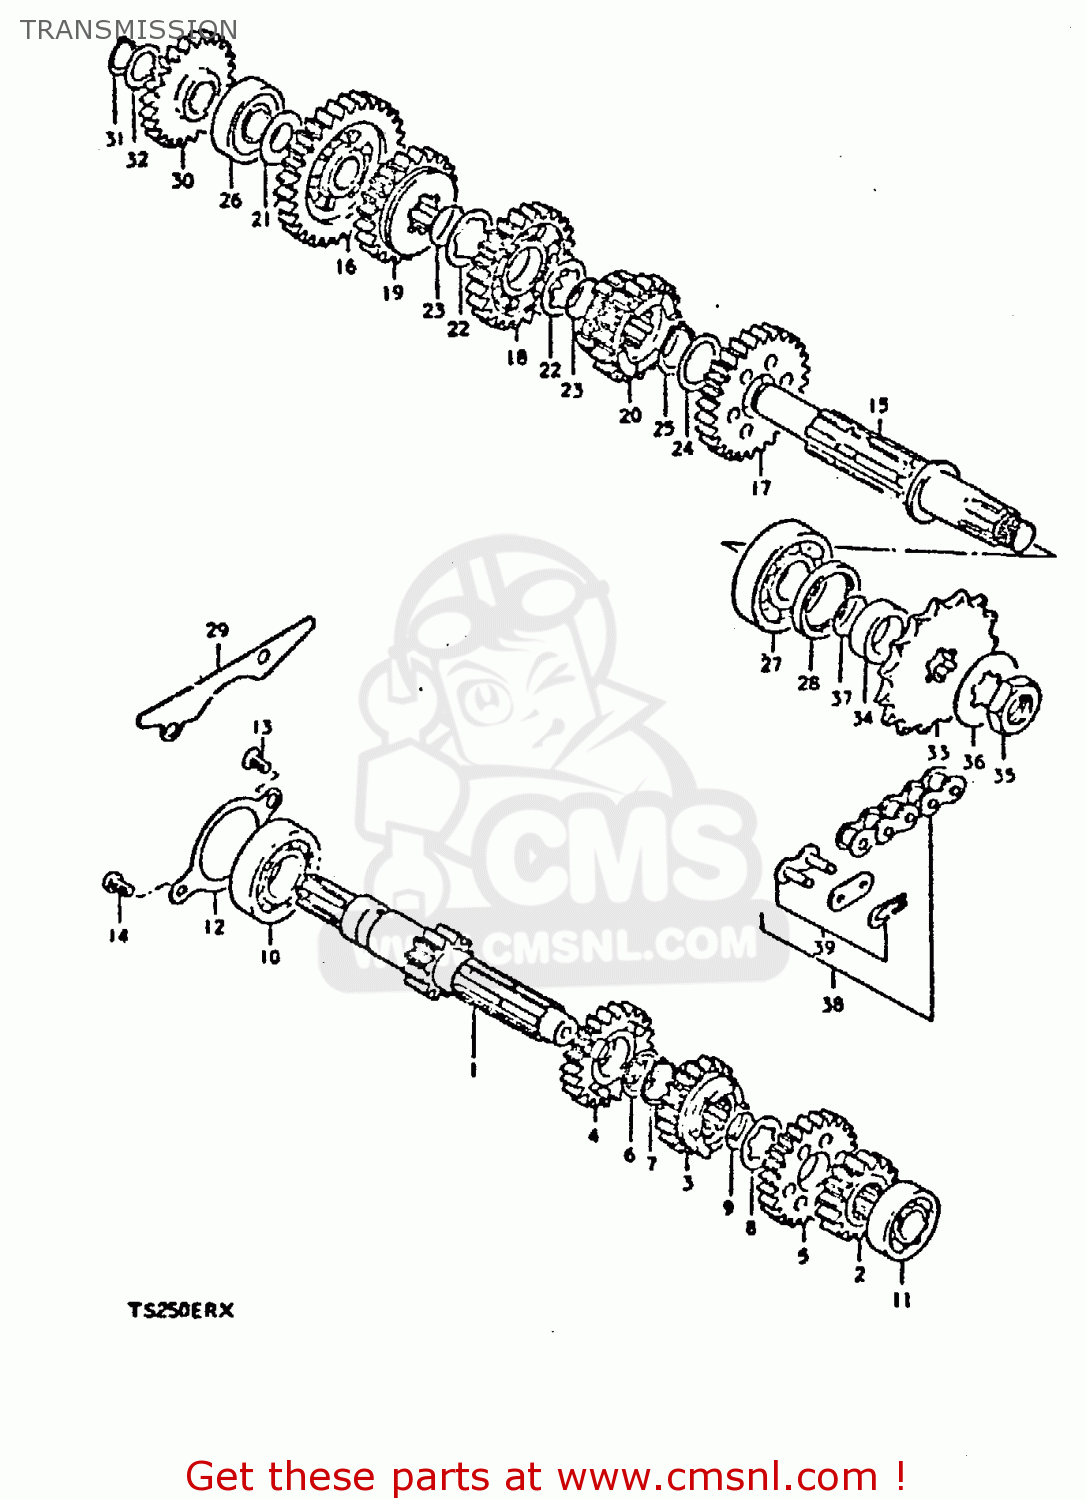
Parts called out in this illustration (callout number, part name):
1	SHAFT,COUNTER
2	GEAR,SECOND DRIVE
3	GEAR,THIRD DRIVE
4	GEAR,FOURTH DRIVE
5	GEAR,FIFTH DRIVE
6	SHIM
7	CIRCLIP
8	WASHER,LOCK
9	CIRCLIP
10	BEARING
11	BEARING
12	PLATE,COUNTERSHAFT BEARING
13	SCREW
14	SCREW 6X12
15	SHAFT,DRIVE
16	GEAR,FIRST DRIVEN
17	GEAR,SECOND DRIVEN
18	GEAR,THIRD DRIVEN
19	GEAR,FOURTH DRIVEN
20	GEAR,5TH DRIVEN
21	WASHER,THRUST
22	WASHER,LOCK
23	RING,SNAP
24	WASHER
25	CIRCLIP
26	BEARING
27	BEARING
28	SEAL,OIL(32X42X6)
29	PLATE,OIL RESERVOIR
30	GEAR,KICK STARTER IDLE
31	CIRCLIP
32	WASHER
33	SPROCKET,ENGINE
34	SPACER(22X32X11.5)
35	NUT
36	WASHER,LOCK
37	O RING(D:1.7,ID:22)
38	CHAIN,DRIVE #525TR-10
39	JOINT ASSEMBLY,CHAIN
